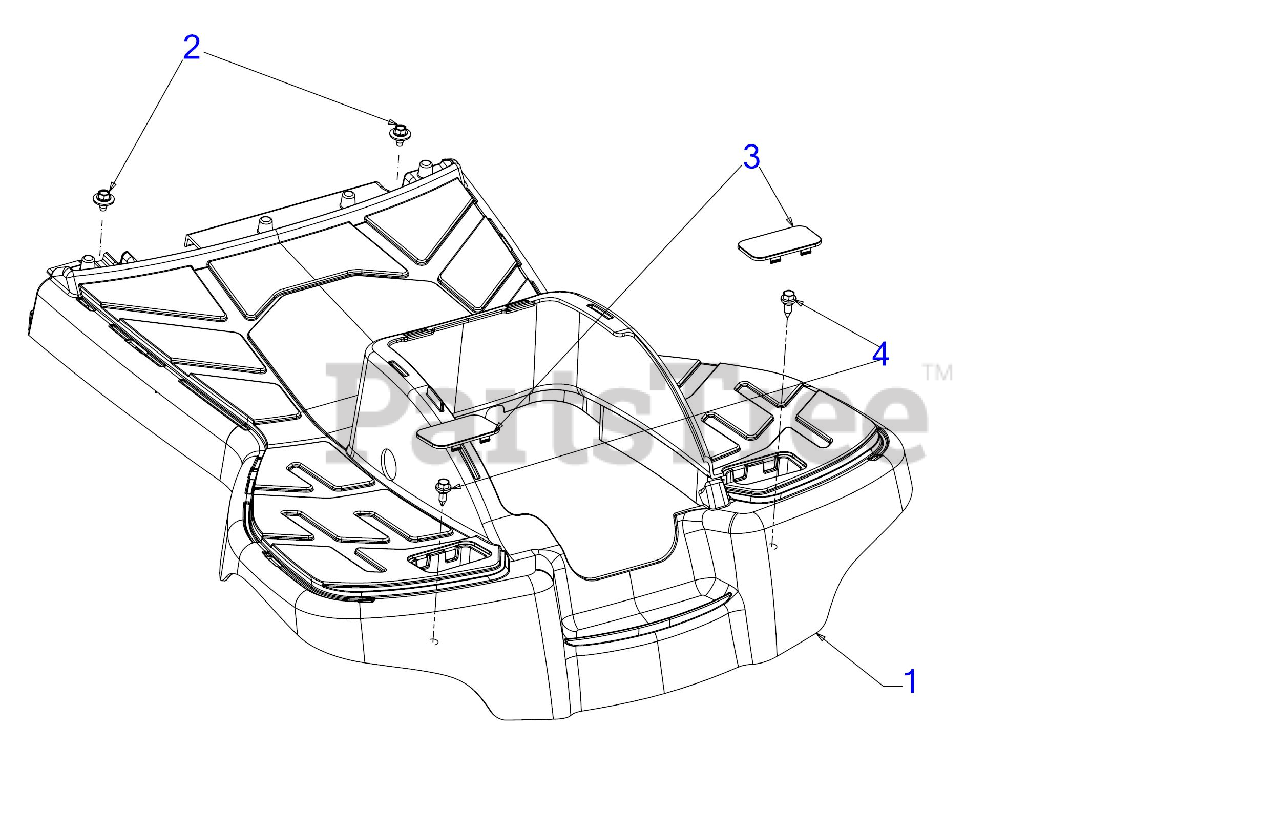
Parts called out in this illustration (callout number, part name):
1	RUNNINGBOARD W/RMC
2	SCREW 1/4-20 x .50
3	RUNNING BOARD PLUG
4	SHOULDER SCREW
